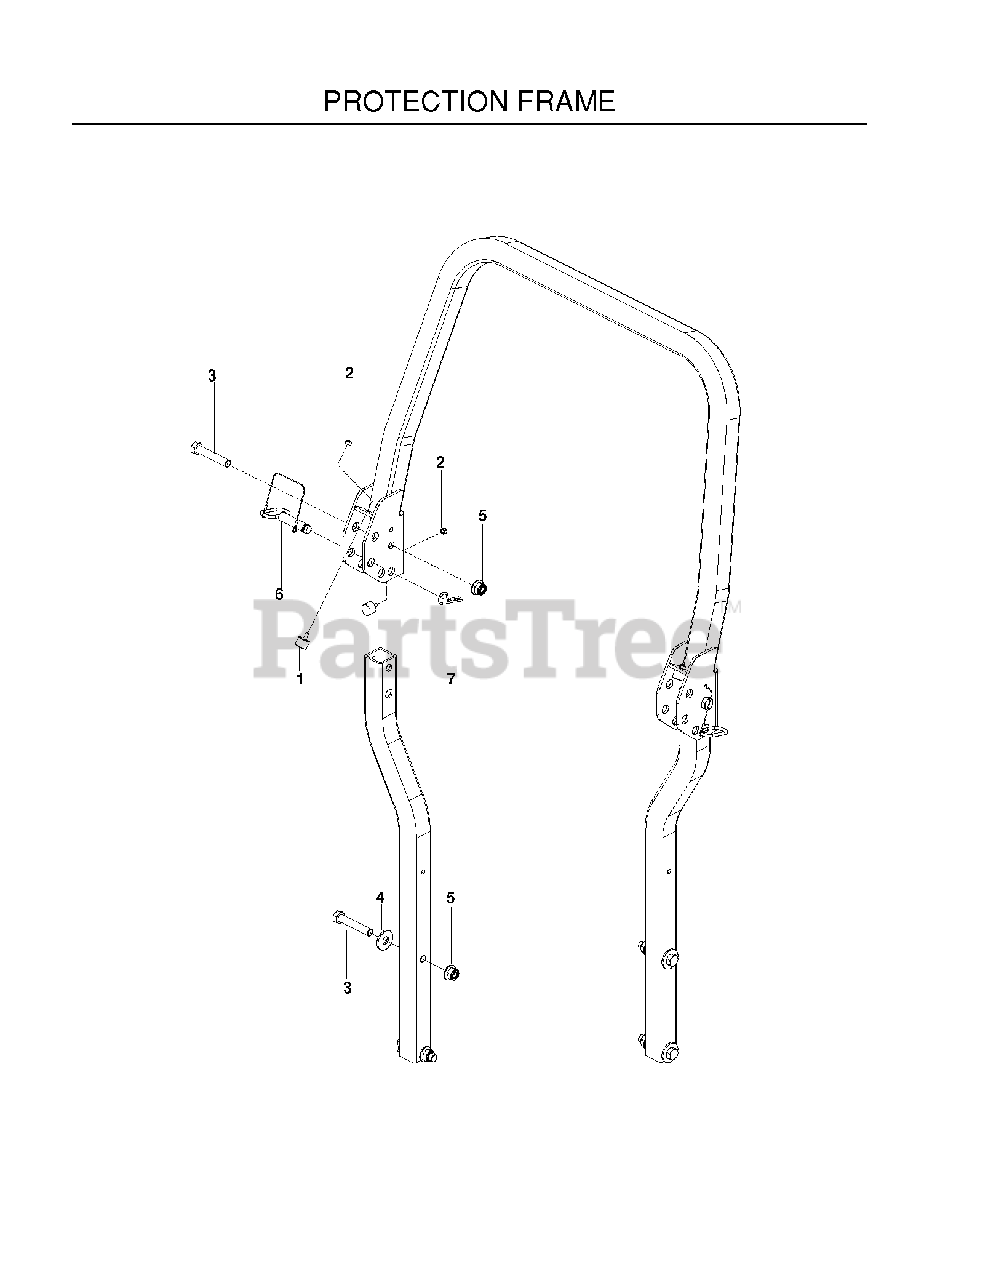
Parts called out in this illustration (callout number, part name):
1	BUMPER, MALE STUD, 1/4-20
2	NUT 1/4-20 NYLOC
3	5/8-11 X 3-1/2 HHB
4	WASHER, 5/8 FLAT
5	NUT 5/8-11 FLG NYLOC ZD
6	PIN, ROPS
7	PIN HAIR .148 X 2-15/16 #210
